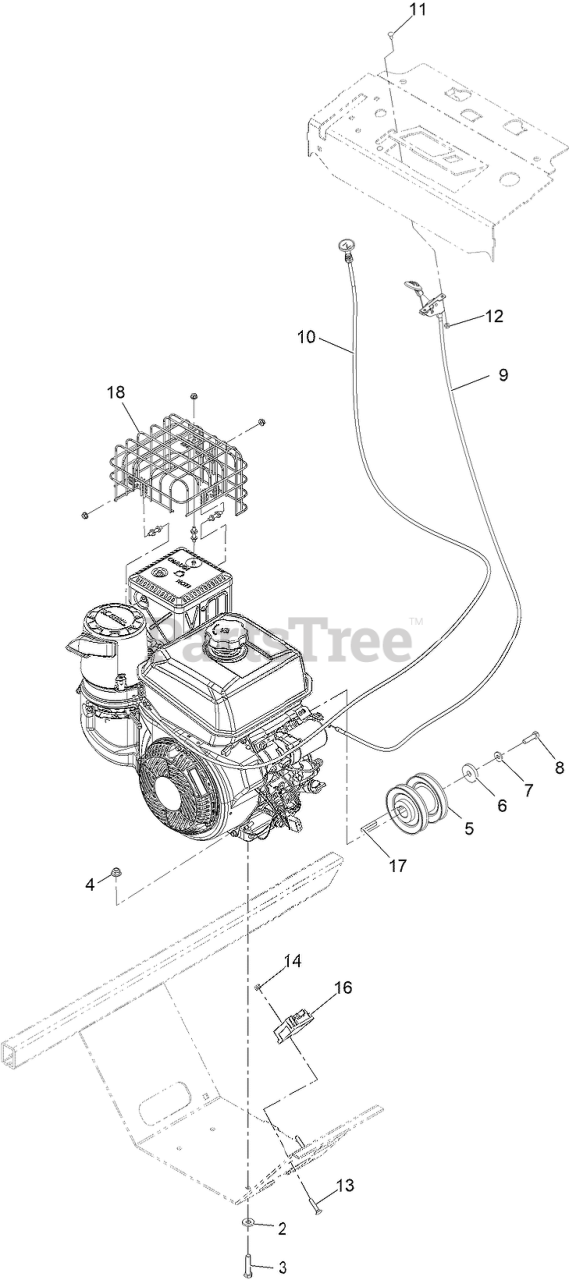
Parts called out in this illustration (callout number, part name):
2	WASHER-BELLEVILLE
3	SCREW-HH
4	NUT-HF, NI
6	WASHER-CLUTCH
7	WASHER-SPRING
8	SCREW-HH
9	CONTROL-THROTTLE
10	CABLE-CHOKE, PUSH/PULL
11	BOLT-CARR
12	NUT-LOCK, NI
13	SCREW-CARR
16	REGULATOR
17	KEY-SQUARE, 7MM
18	KIT-MUFFLER BIRDCAGE
